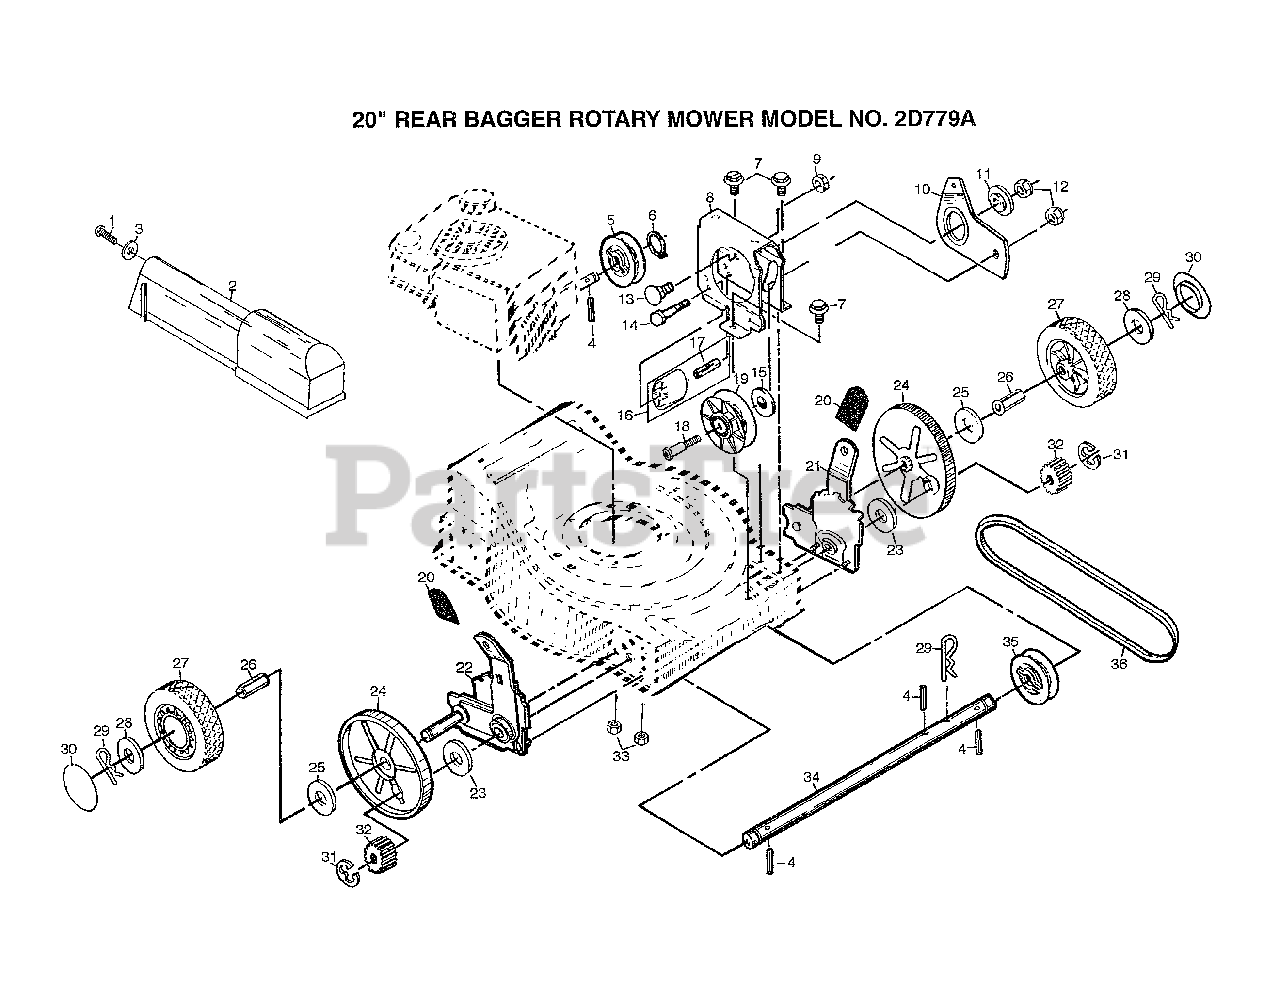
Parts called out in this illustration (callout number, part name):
1	TAPPING SCREW
4	DRIVE PAWL
6	RETAINING RING ST
7	SCREW
8	"CLUTCH,FRAME"
9	LOCKNUT
11	SPACER PM
12	LOCKNUT
13	CARRIAGE BOLT
14	BOLT 1/4-20-1 1/2
15	SPACER PM
17	IDLER SPACER
18	SHOULDER BOLT
19	IDLER PULLEY
20	KNOB PM
23	WASHER PM
24	DUST SHROUD PM
25	WASHER FLUT
26	BUSHING.HEX
27	WHEEL.8X2.LP.PR
28	WASHER
29	RETAINER CLIP PM
30	HUB CAP
31	E-RING.7/16.RE.
32	PINION.GEAR
34	SHAFT.DRIVE.17.81
35	DRIVE PULLEY PM
36	"DRIVE, BELT"
